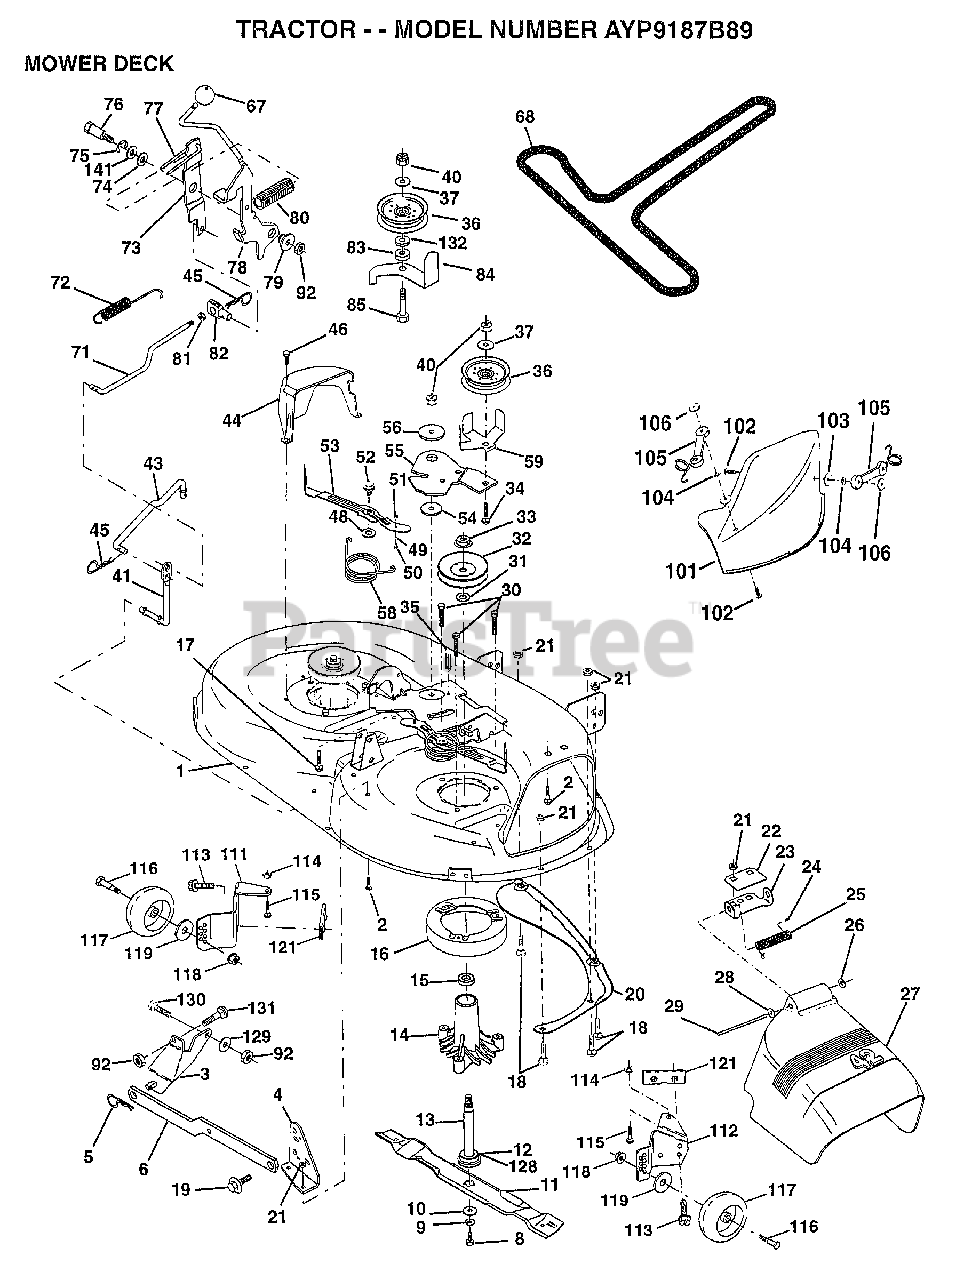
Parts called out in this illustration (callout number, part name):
1	"HOUSING ASSY.42"""
2	BOLT
3	BRKT ASM SWAY BAR
4	BRKT DECK SW BAR
8	BLADE BOLT
10	WASHER.HARD.BLADE
11	"BLADE.42"" MULCHER"
12	BEARING.BALL
14	HSG ASM MANDREL
15	BEARING
16	STRIPPER RND MWR
17	BOLT RDHD 3/8-16
18	BOLT
19	BOLT SHD 5/16-18
20	BAFFLE VORTEX 42
22	STIFFENER BRKT
23	DEFLECTOR BRKT
25	SPRING TORSION
27	DEFLECTOR.SHIELD
28	WASHER
29	HINGE ROD
30	"SCREW-THD ROLL,WA"
31	WASHER
32	PULLEY.MANDREL.42
34	BOLT
35	XMAS TREE FASTNER
36	FLAT IDLER PULLEY
37	WASHER
41	PIVOT ROD
43	ROD CLUTCH W/NIBS
44	GUARD MAND LH BLK
46	SCREW.1/4-20X5/8
48	HARD SMALL WASHER
49	ROLLER ASM-CAM
50	SHOULDER BOLT
51	LOCKNUT
52	BOLT.SHLD.5/16-18
53	BRAKE PAD ARM ASM
54	HARDENED WASHER
55	ARM-IDLER
56	SPACER RETAINER
58	SPRING TORSN BRAK
59	GUARD IDLER TUV
67	KNOB.RD.7/16-14
68	BELT.V.T-PATH
71	ROD CLUTCH 38/42
72	RETURN SPRING
73	CLUTCH ARM SECOND
74	WASHER
75	RING
76	SHOULDER BOLT
77	SPRING KEEPER
78	LEVER.ASM.CLUTCH
79	BUSHING
80	SPRING.CLUTCH.MWR
81	NUT
82	TRUNION ADJ
83	WASHER
84	"KEEPER-BELT,FIXED"
85	BOLT
92	NUT
101	"COVER.MULCH.42"""
102	SCREW
103	WASHER #10
104	LOCKWASHER
105	LATCH ASSY.BAGGER
106	WELDNUT
111	BRACKET.GWHL.LH.
112	BRACKET.GWHL.RH.
113	SCREW
116	BOLT.SHOULDER
117	WHEEL GAGE DONUT
118	LOCKNUT
119	WASHER
121	BRACKET.EXTRD.GWL
128	WASHER.FELT.
129	WASHER
130	BOLT
132	WASHER GT
141	WASHER .T
